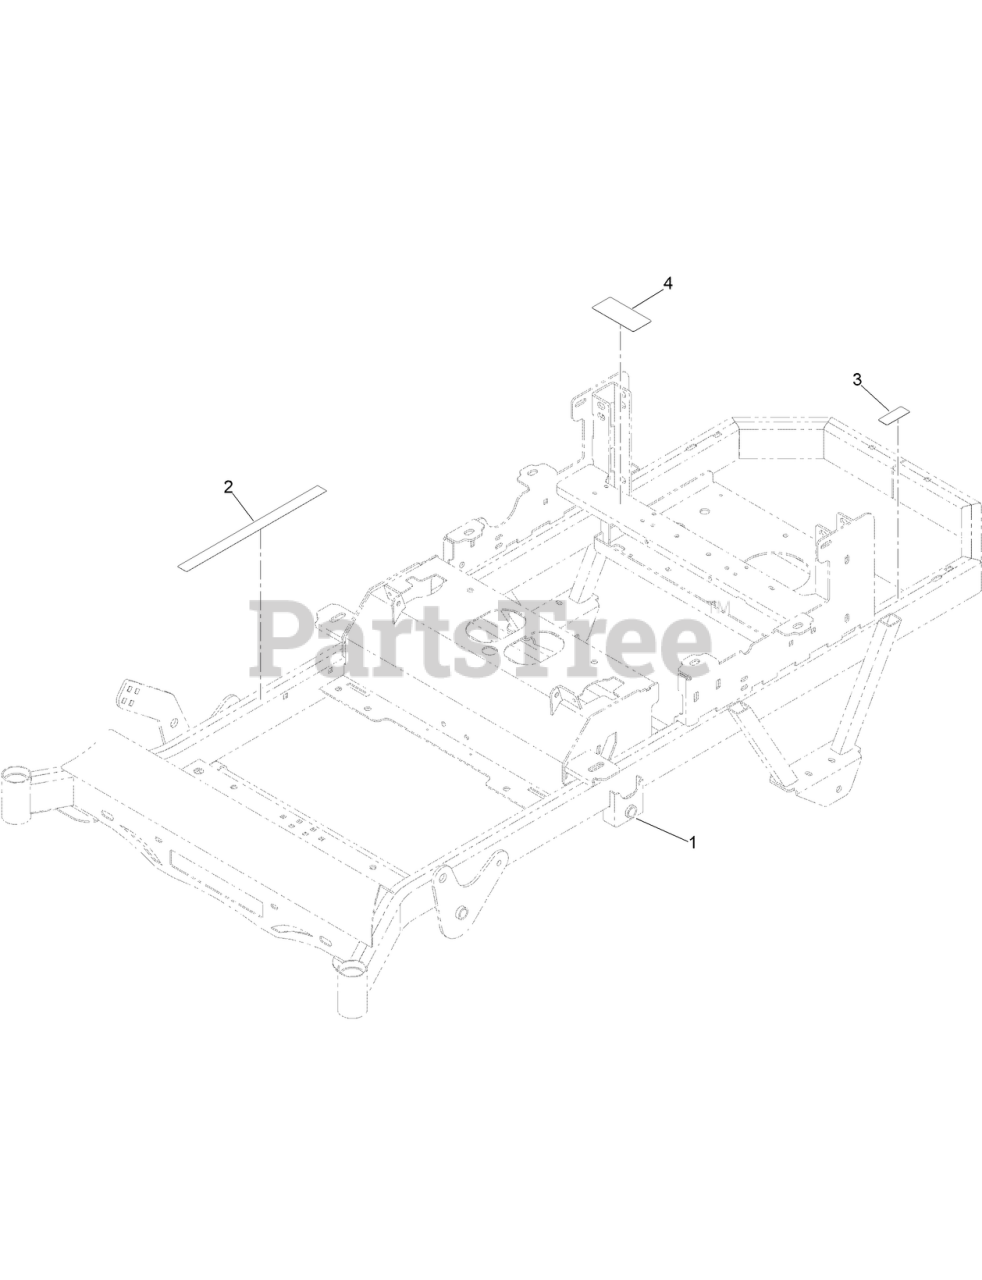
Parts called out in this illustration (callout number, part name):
1	FRAME
2	DECAL-WARNING(AURORA)
3	DECAL-HOT SURFACE
4	DECAL-ROTATING FAN HAZARD
